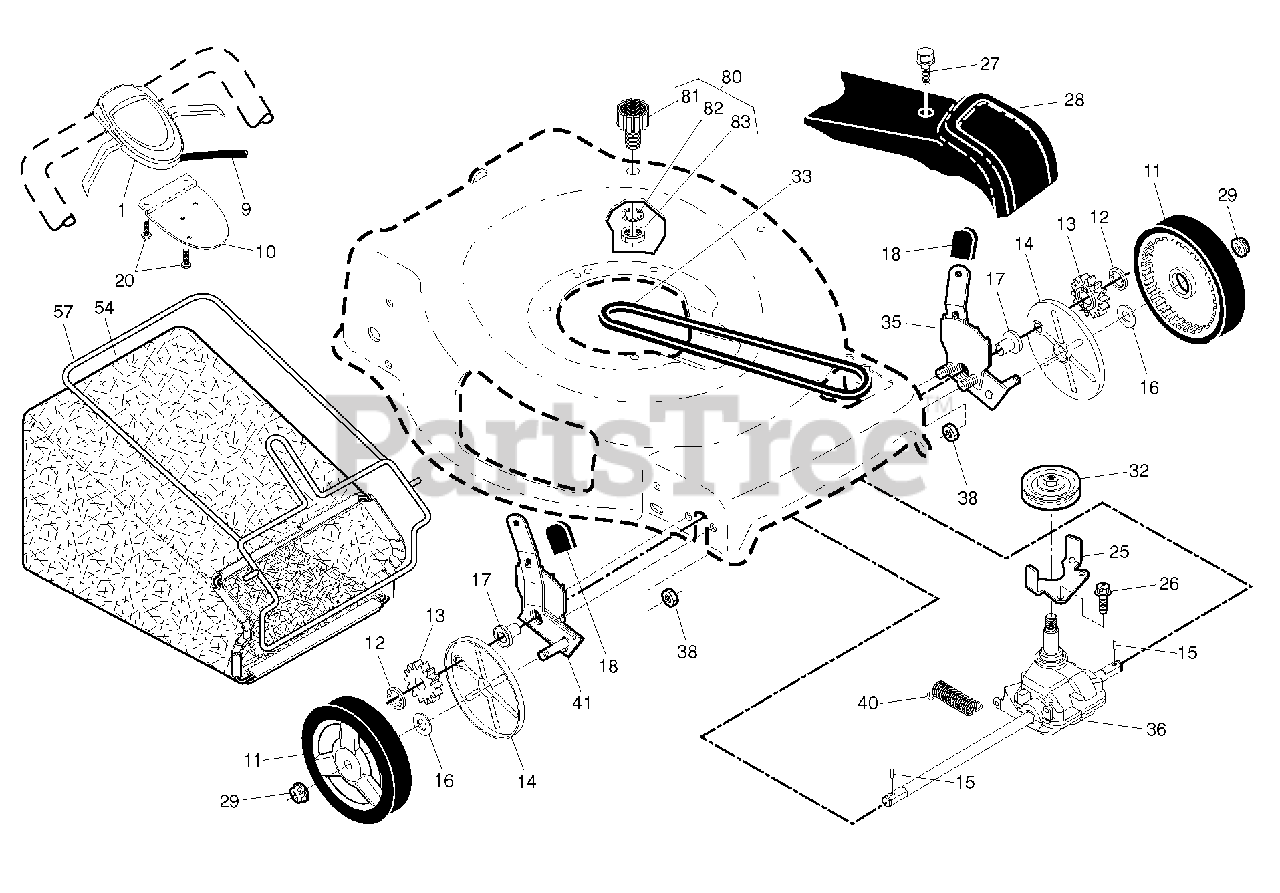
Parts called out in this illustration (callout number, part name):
1	CONTROL.AW2.22FG.BS.GRAY/BLACK
9	CABLE.CONTROL.22FGD.GEN2
10	BRACKET.DRIVE.CONTR.GEN2.BLACK
11	WHEEL.8X1.75.H3SPK.RAD3.GY.BU3
12	E-RING 7/16 RE
13	PINION.14.TEETH.FGD
14	COVER.DUST.WHEEL
15	PAWL, DRIVE
16	WASHER FLUT
18	SELECTOR KNOB
20	SCREW, PHILLIPS HEAD 10 X 5/8
25	BRACKET.BELT.GUIDE.22+FGD.BZP
28	COVER.DRIVE.22.LABEL.HUSQVARNA
29	NUT.HEX.FLANGE.3/8-16.LO(3 2)
32	RP PULLEY.DRIVE.EZ/VAR.SCREWON
33	BELT.DRIVE.FWD.
35	ADJUSTER.ASM.9.22+/RF/LR.21/RF
36	TRANSMISSION.22PLUS.FGD.AW2/EZ
38	NUT.HEX.FLANGE.1/4
41	ADJUSTER.ASM.9.22+/RF/LR.21/LF
54	GBAG.A3610247T.SILV.HUSWT.BLUE
57	RB FRAME.GBAG.22PLUS
80	KIT.WASH-OUT.PORT
81	FITTING, HOSE, WATER WASHOUT
82	WASHER.LOCK.INTERNAL.TOOTH
83	LOCKNUT.HEX.WITH.O-RING
84	COUPLING.QUICK CONNECT
